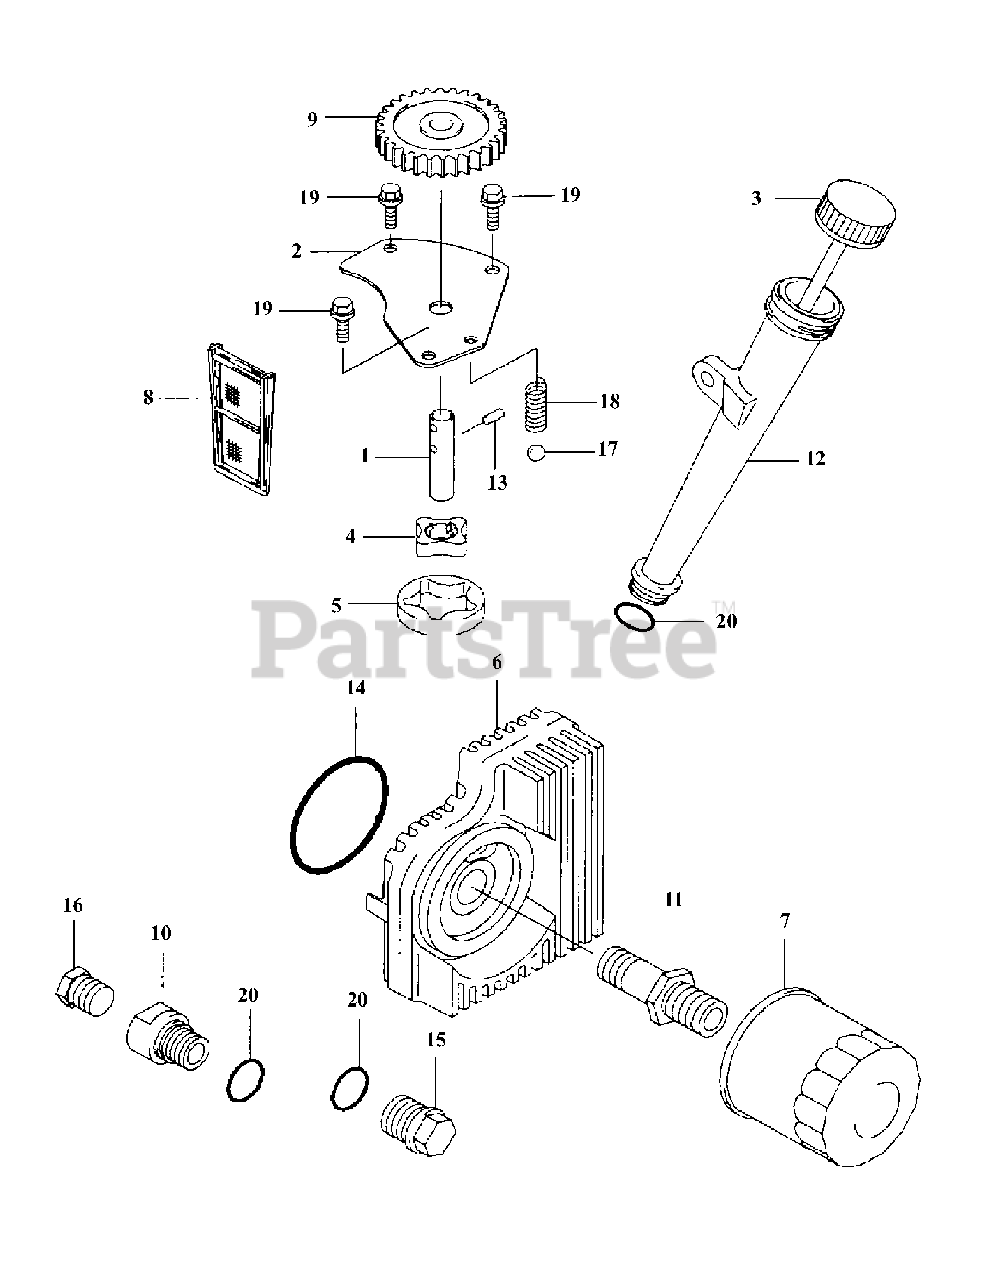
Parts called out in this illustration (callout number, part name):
1	Shaft
4	Rotor-Pump,in
5	Rotor-Pump,out
6	Cooler-Oil
7	Filter-Oil
8	Filter-Oil Screen
9	Gear-Spur
10	Joint
11	Joint
13	Pin
15	Plug
16	Plug
